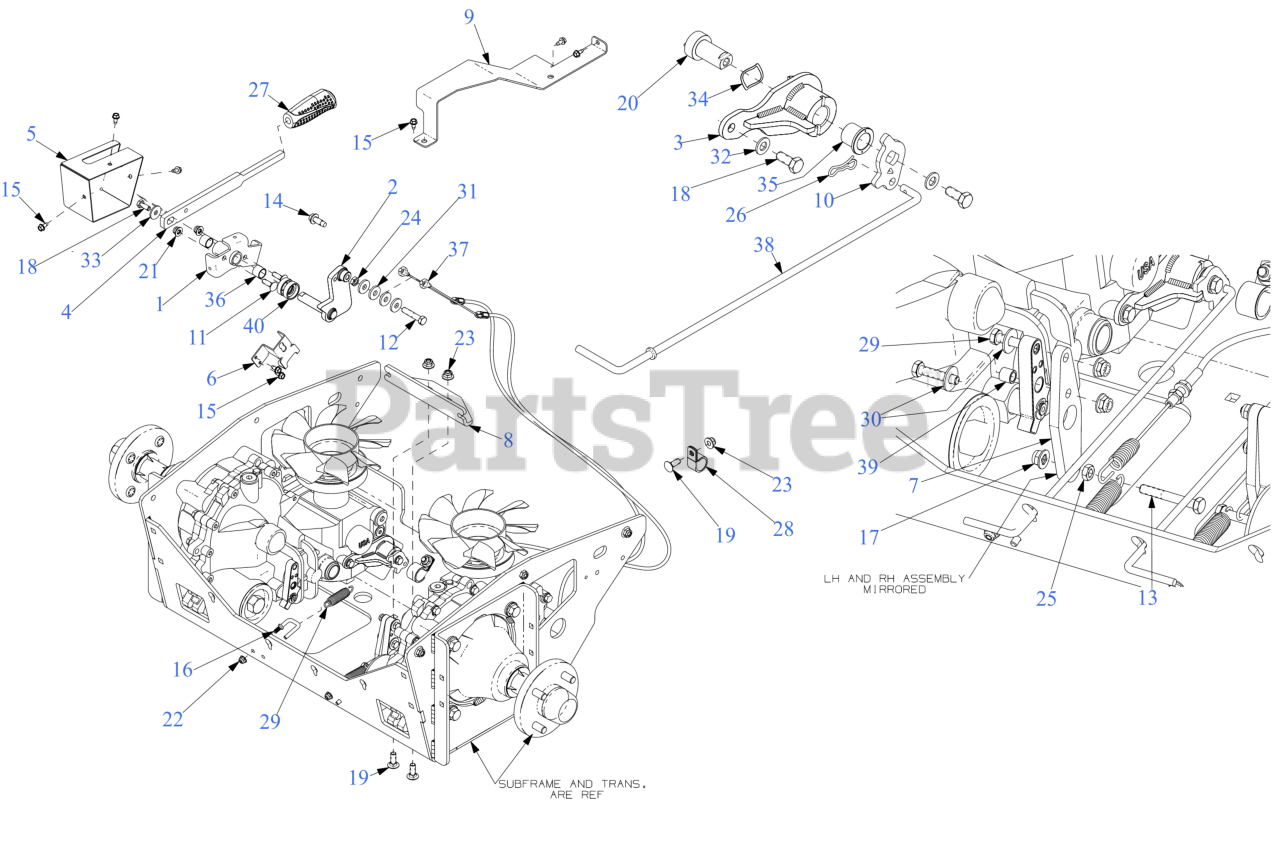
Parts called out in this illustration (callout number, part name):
1	PIVOT TUBE ASSEMBLY
2	BRAKE PIVOT SHAFT
3	ACTUATOR BRACKET
6	3-POLE SWITCH BRACKET
7	BRAKE ARM PLATE
8	CABLE BRACKET
9	BRAKE LEVER COVER
10	BYPASS LEVER BRACKET
11	CARRIAGE BOLT 5/16-18 x 1.00
12	HEX SCREW 3/8-16 x 1.75 GR5
13	HEX SCREW 5/16-18 x 2.25 GR5
14	SCREW 3/8-16 x 1
15	SCREW 1/4-20 X.500
16	EYE BOLT SPRING GUIDE 1/4-20
17	SCREW 5/16-18 x 1.5 LG
18	SCREW 5/16-18 x .750
19	CARRIAGE BOLT 3/8-16 x 1.00 GR5
20	ACTUATOR BYPASS SHAFT
21	FLANGE LOCK NUT 5/16-18
22	FLANGE LOCK NUT
24	HEX JAM NUT 3/8-16 GR5
25	HEX NUT TOP LOCK 5/16-18 GR 8
26	BOW TIE COTTER PIN 1/4-5/16
28	HOSE CLAMP 1.0"
29	EXTENSION SPRING .65 OD x 2.65 LG
30	FLAT WASHER
31	FLAT WASHER .385 x 1.00 x .135
32	FLAT WASHER
33	FLAT WASHER 1.0 OD:.331 ID
34	WAVE WASHER .785X1.00X.012
35	FLANGE BEARING .625 X .75 X .75
36	SLEEVE BEARING
37	PARK BRAKE CABLE
38	BYPASS ROD
